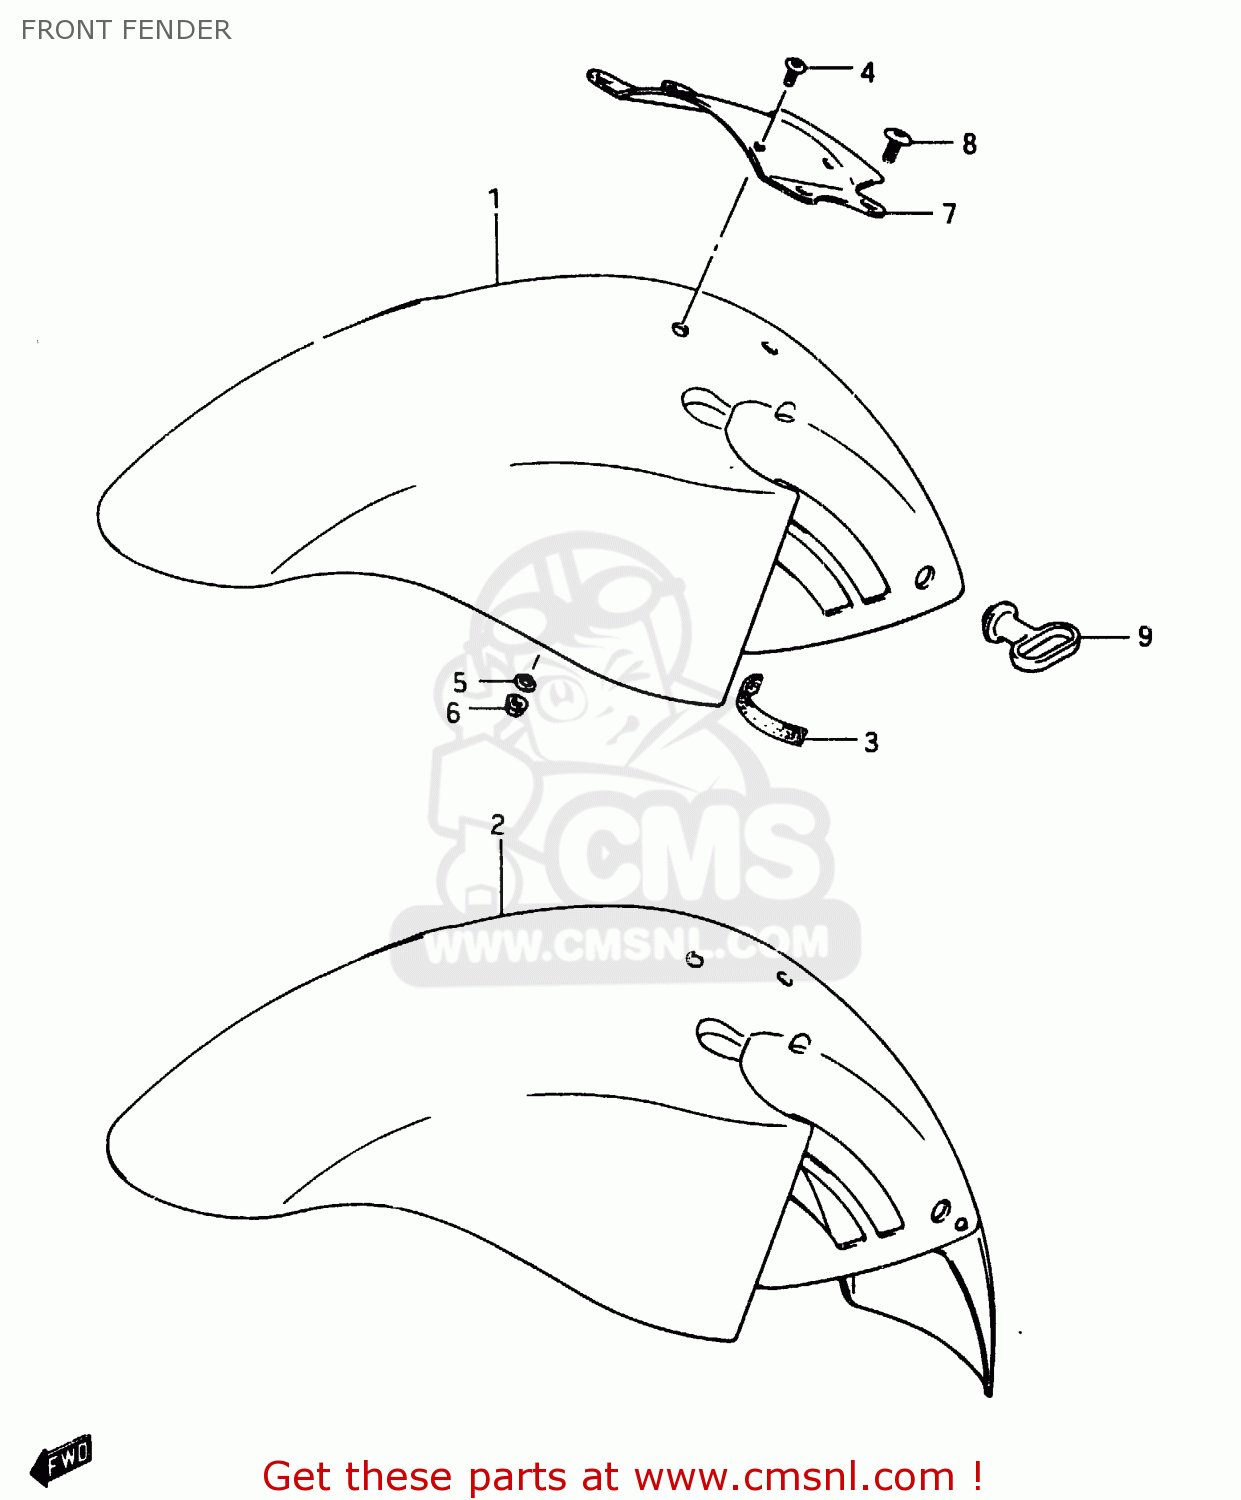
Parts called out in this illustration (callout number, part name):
1	FENDER,FRONT
2	FENDER, FRONT (WHITE)
3	CUSHION,FR FENDER
4	SCREW(5X14)
5	WASHER
6	NUT
7	BRACE, FRONT FENDER
8	SCREW(6X12)
9	GUIDE,CABLE
